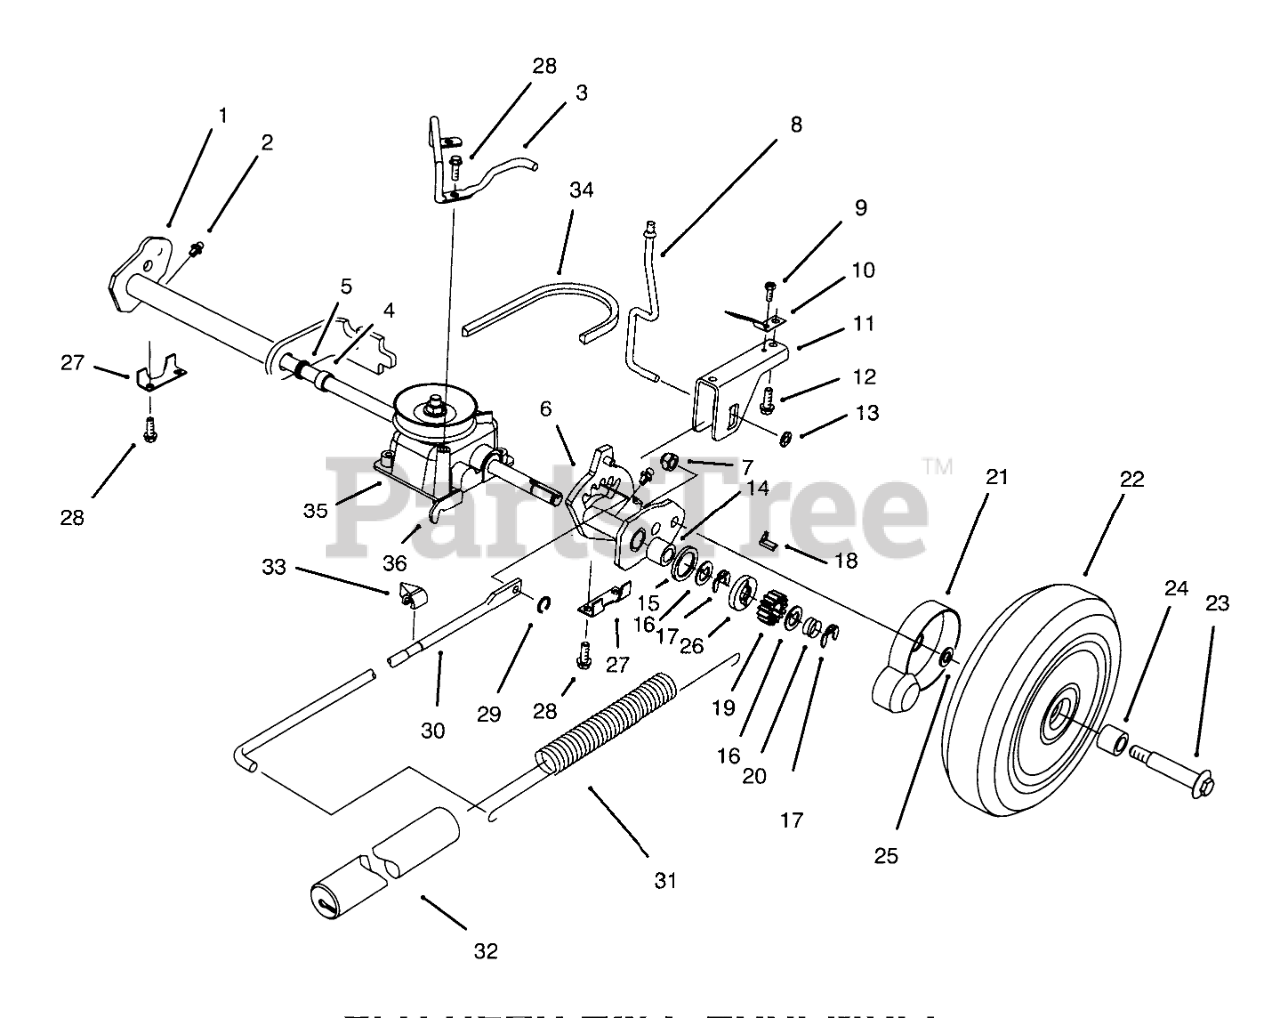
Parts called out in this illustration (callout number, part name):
1	Rear Pivot Assembly R.H. (Incl. Ref. #2, 4, 5 & 14)
2	FITTING-GREASE
3	Retainer Belt
4	BUSHING
5	SEAL-OIL
6	Assembly L.H. (Incl. Ref. #2, 4, 5 & 14)
7	NUT-HEX
8	TRIGGER ROD
9	SCREW 8 - 32 X 250
10	SPRING - TRIGGER RET
11	SADDLE - HOC
12	SCREW
13	PUSHNUT
14	BEARING-ROLLER
15	RING-FRICTION
16	WASHER-THRUST, KEYED
17	RING-CLIP, LOCKING
18	KEY-ROCKING, LH
19	GEAR-PINION
20	SPRING-COMPRESSION
21	COVER-WHEEL
22	Wheel, Tire & Gear Assy. (Incl. Ref. #24)
23	BOLT-WHEEL
24	BUSHING
25	SPACER-COVER, WHEEL
26	WASHER-CLUTCH
27	REAR SECURING PLATE
28	SCREW-HWH
29	GRIP RING
30	LINK ROD
31	SPRING-COUNTERBALANCE
32	COVER-SPRING
33	INDICATOR-HEIGHT OF CUT
34	V-BELT
35	Gearcase Assembly (Incl. Ref. #36)
36	Bracket-Traction
